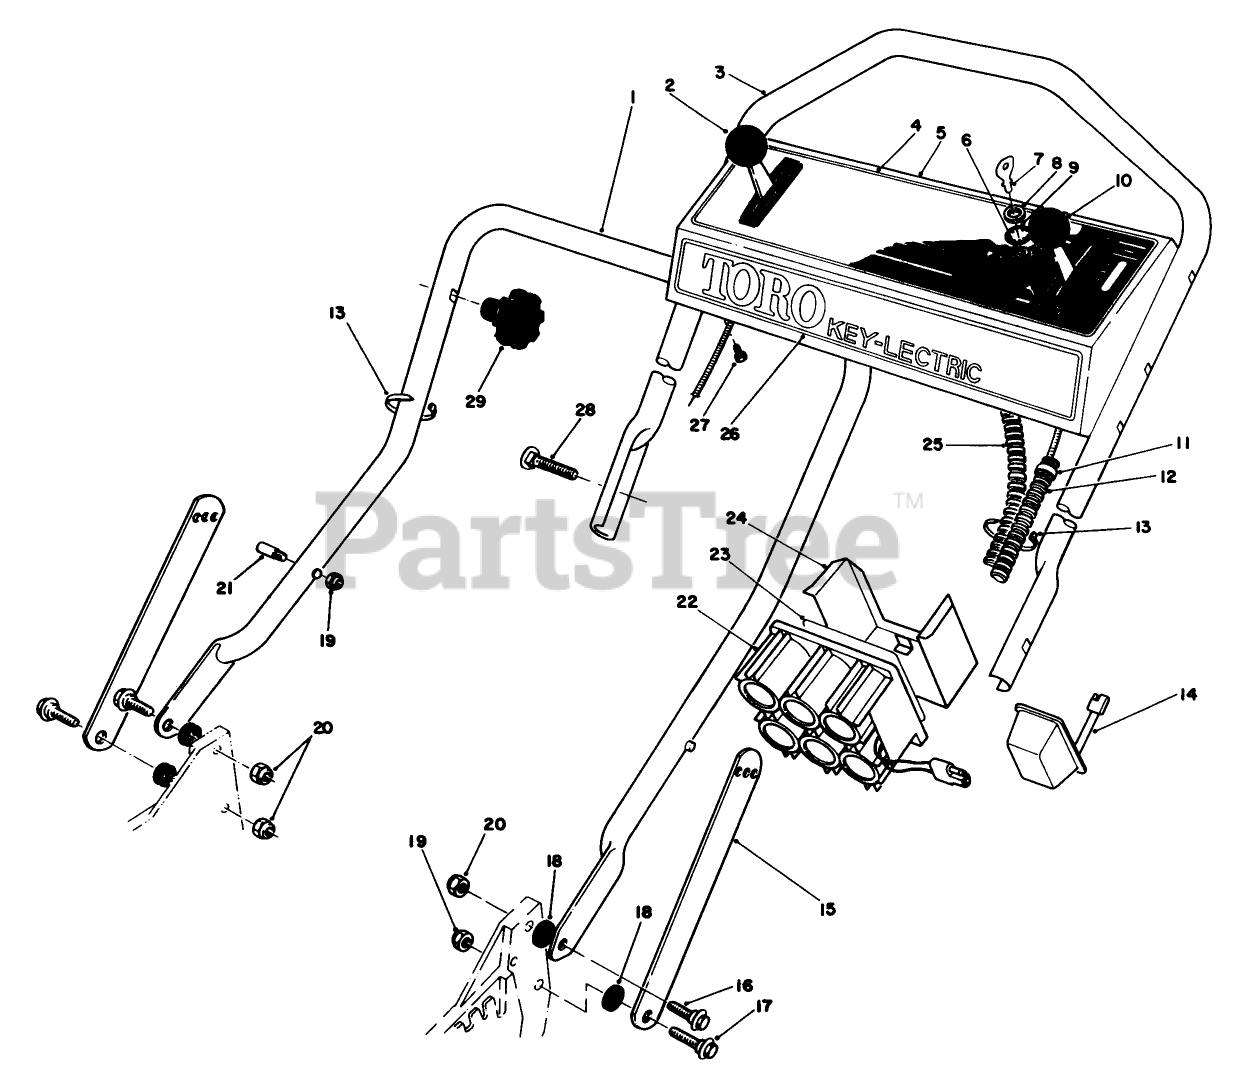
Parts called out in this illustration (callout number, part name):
2	SERVICE THROTTLE CONTRO
6	STARTER SWITCH ASM
8	NUT-HH
9	WASHER-LOCK
10	SERVICE TRACT. CONTROL
11	FITTING-RING
13	TIE-CABLE
16	SCREW-SHOULDER
17	SCREW-SHOULDER
18	SPACER
19	NUT-LOCK, NI
20	NUT-LOCK, NI
21	HANDLE PIN
22	BATTERY ASSEMBLY,WET
25	WIRE HARNESS
27	SCREW-HWHTF
